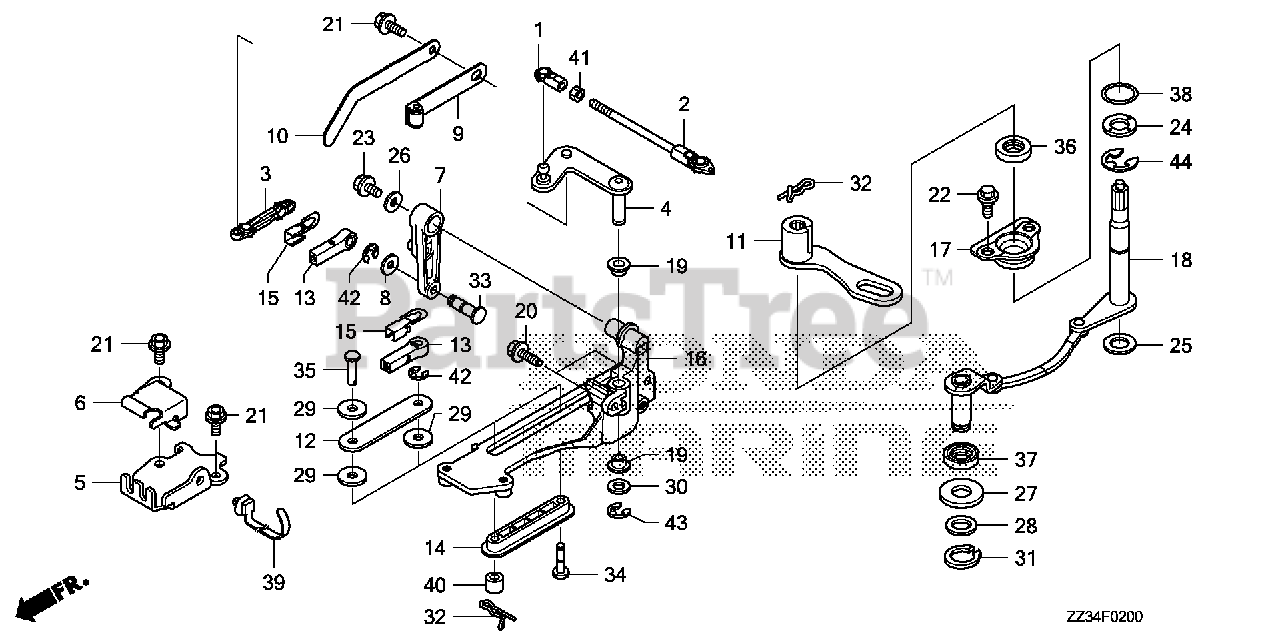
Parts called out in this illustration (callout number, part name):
1	LINKAGE, PIVOT
2	ROD, THROTTLE
3	LINK, THROTTLE
4	PLATE, THROTTLE
5	PLATE, REMOTE CONTROL CABLE
6	COVER, REMOTE CONTROL CABLE
7	ARM, THROTTLE
8	WASHER, PIVOT
9	SPRING, CLICK
10	SPRING, CLICK ASSIST
11	ARM, SHIFT
12	PLATE, SHIFT PIVOT
13	PIVOT, SHIFT
14	PIVOT, SHIFT SLIDE
15	PLATE, LOCK
16	BRACKET, SHIFT LINK
17	HOLDER, SEAL
18	SHAFT, SHIFT
19	BUSH A, COVER LOCK
20	BOLT, FLANGE (6X18) (CT200)
21	BOLT, FLANGE (6X16)
22	BOLT, FLANGE (6X11)
23	BOLT, FLANGE (6X12)
24	WASHER, SIDE (14MM)
25	WASHER, SHIFT SHAFT
26	WASHER, PLAIN (6MM)
27	WASHER (14MM)
28	WASHER (13MM)
29	WASHER, NYLON (8MM)
30	WASHER, PLAIN (8MM)
31	CIRCLIP (OUTER) (12)
32	PIN, SNAP (6MM)
34	PIN, SHIFT LINK
36	OIL SEAL (14X26X6)
37	SEAL, WATER (14X26X8)
38	O-RING (26.9X2.4) (NOK)
39	CLIP, HARNESS BAND (155.3MM) (BLACK)
40	COLLAR (6MM)
41	NUT, HEX. (5MM)
42	E-RING (4MM)
43	E-RING (6MM)
44	E-RING (12MM)
